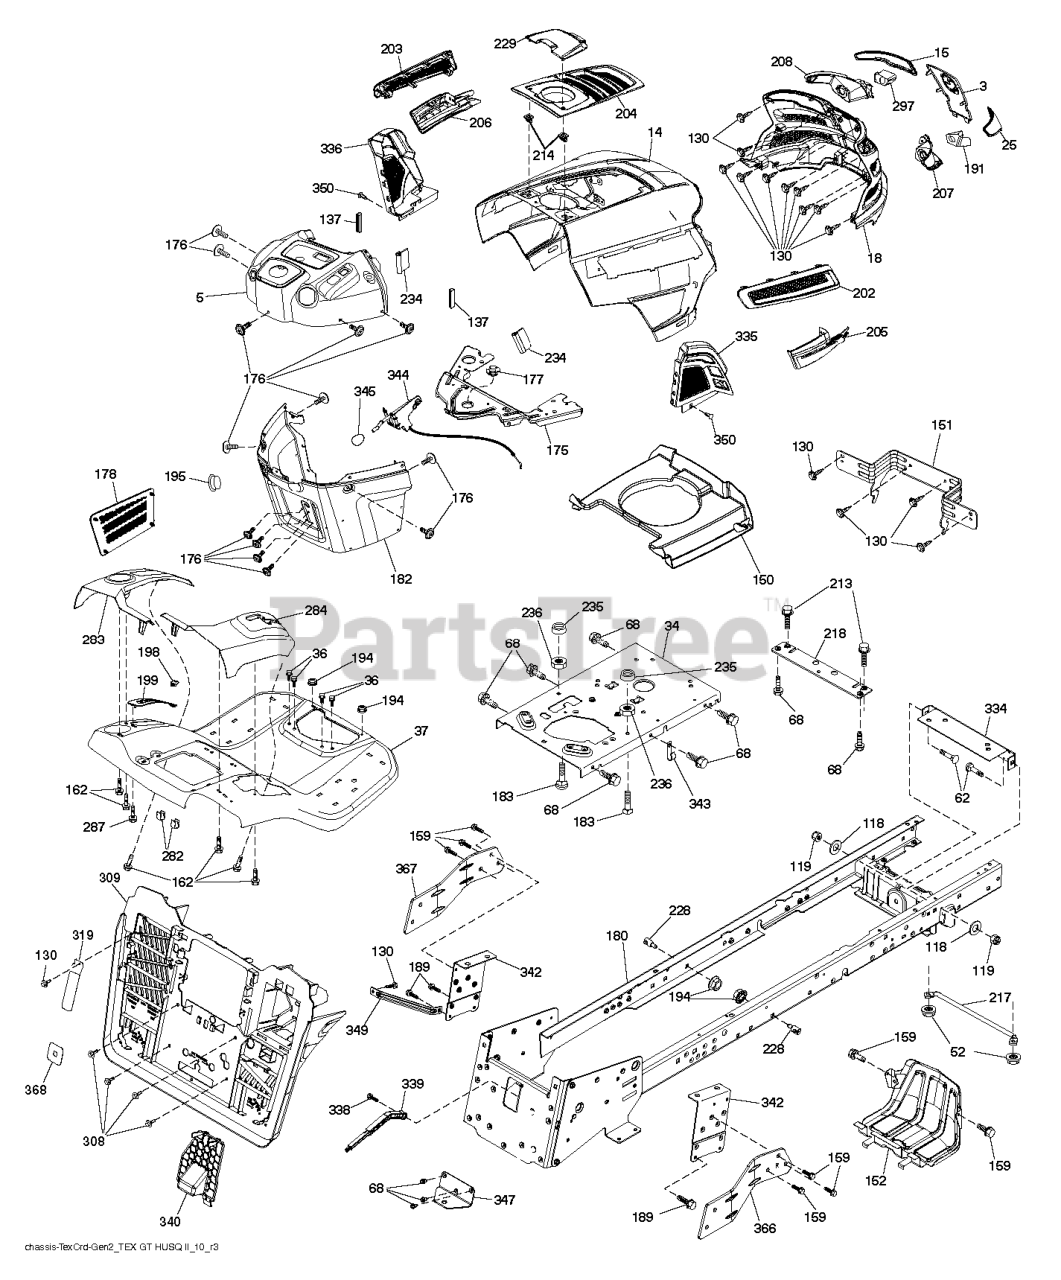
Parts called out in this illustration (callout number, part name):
3	APPLIQUE.SUBASM.GT.HUSQ.II
14	HOOD.ASM.HUSQVARNA.GT.TEX.ORAN
15	LENS.HEADLIGHT.LH.GTII.2011
18	GRILLE.SUBASM.GT.HUSQ.II
25	LENS.HEADLIGHT.RH.GTII.2011
34	PLATE.ENGINE.WELDED.CHASSIS
36	SCREW 5/16"
37	FENDER.TEX.SRD.CRD.FRN.GUARDS
52	LOCKNUT
62	BOLT D
68	SCREW LT
118	WASHER
130	SCREW.#10 X 0.750.BOS
137	BUMPER DASH
150	AIR DUCT.GTV2(1.66"RING HEIGHT
151	BRACKET.PIVOT.HOOD.GT.HUSQ.II
152	SHIELD.BROWNING.PNT.GT.V2
159	SCREW, 3/8-16X3/4
162	SCREW.HI-LO.CONSOLE
175	PLATE.CROSSMEMBER.HUSQ
176	SCREW.#10-24X5/8.RN.QU
177	BUSHING, STEERING
178	CARGO.ASM.NET.TXGT.W/C
180	WELDMENT.CHASSIS.TEX.CRD.GEN.2
182	DASH DASH LOWER
183	BOLT.5/16-18X1-1/4 FULL THD
189	SCREW
191	INSERT.REFLECTIVE.RH.HUSQ.GTII
194	NUT LOCK HEX FLANGE 5/16-18
195	PLUG.HOLE.DASH.LOWER.12V.BLK
198	INDICATOR.DECK.LIFT.RED
199	PLATE DECK LIFT
202	VENT.SIDE.RH.GT.HUSQ.II.
203	VENT.SIDE.LH.GT.HUSQ.II.498
204	VENT.TOP.EXTERNAL.FILL.GT2.GRE
205	SIDE.TRIM.RH.GT.HUSQ.II
206	SIDE.TRIM.LH.GT.HUSQ.II.GRAY
207	BEZEL LIGHT.RH.GT.II.MYLAR
208	BEZEL LIGHT.LH.GT.II.MYLAR
213	BOLT
214	CLIP.RETAINER.TINNER.
217	ROD.PIVOT.HOOD
218	X-PIECE.HOOD.STOP.NON/
228	STUD.FASTNER.W/ANTI-ROTATE
229	LID.EXT.FILL.GT.HUSQ2.BLACK
234	BUMPER.HOOD.TEX.HUSQVARNA
235	SPACER FENDER
236	NUT.CENTERLOCK.5/16-
282	CLIP.RETAINER.CONSOLE.LT.HUSQ
283	CONSOLE.DECKLIFT.CRDII.498
284	CONSOLE.PEDAL.HYDRO
287	SCREW 1/4X20
297	INSERT.REFLECTIVE.LH.HUSQ.GTII
308	BOLT.5/16-18UNCX3/4 W/SEMS.BLK
309	BACKPLATE.ASM.CRDII.ANTIROTAT
319	LEVER.BAG.CRDII.ANTIROTATION
334	BRACKET.ENGINE
335	COVER.LOWER.DASH.RH.BLACK
336	COVER-LH.LOWER.DASH.GT2.BLACK
338	BOLT BOLT SHOULDER
339	LEVER LEVER BAGGER
340	BATTERY.DOOR.TEX.CRD.GEN.2,1
342	SUPPORT SUPPORT FENDER
343	CLIP CLIP
344	CONTROL.EZ.MULCH.TEX/CRD
345	RP KNOB.OVAL.TAPERED.3/8-16BLK
347	HITCH TOW
349	BRACKET.SUPPORT.LRVB/CRD
350	CLIP.X-MAS.TREE
366	BRACKET.RH.FRONT.BAGGER.BLACK
367	BRACKET.LH.FRONT.BAGGER.BLACK
368	FULL.LEVER.BAGGER.TEX.CRD
